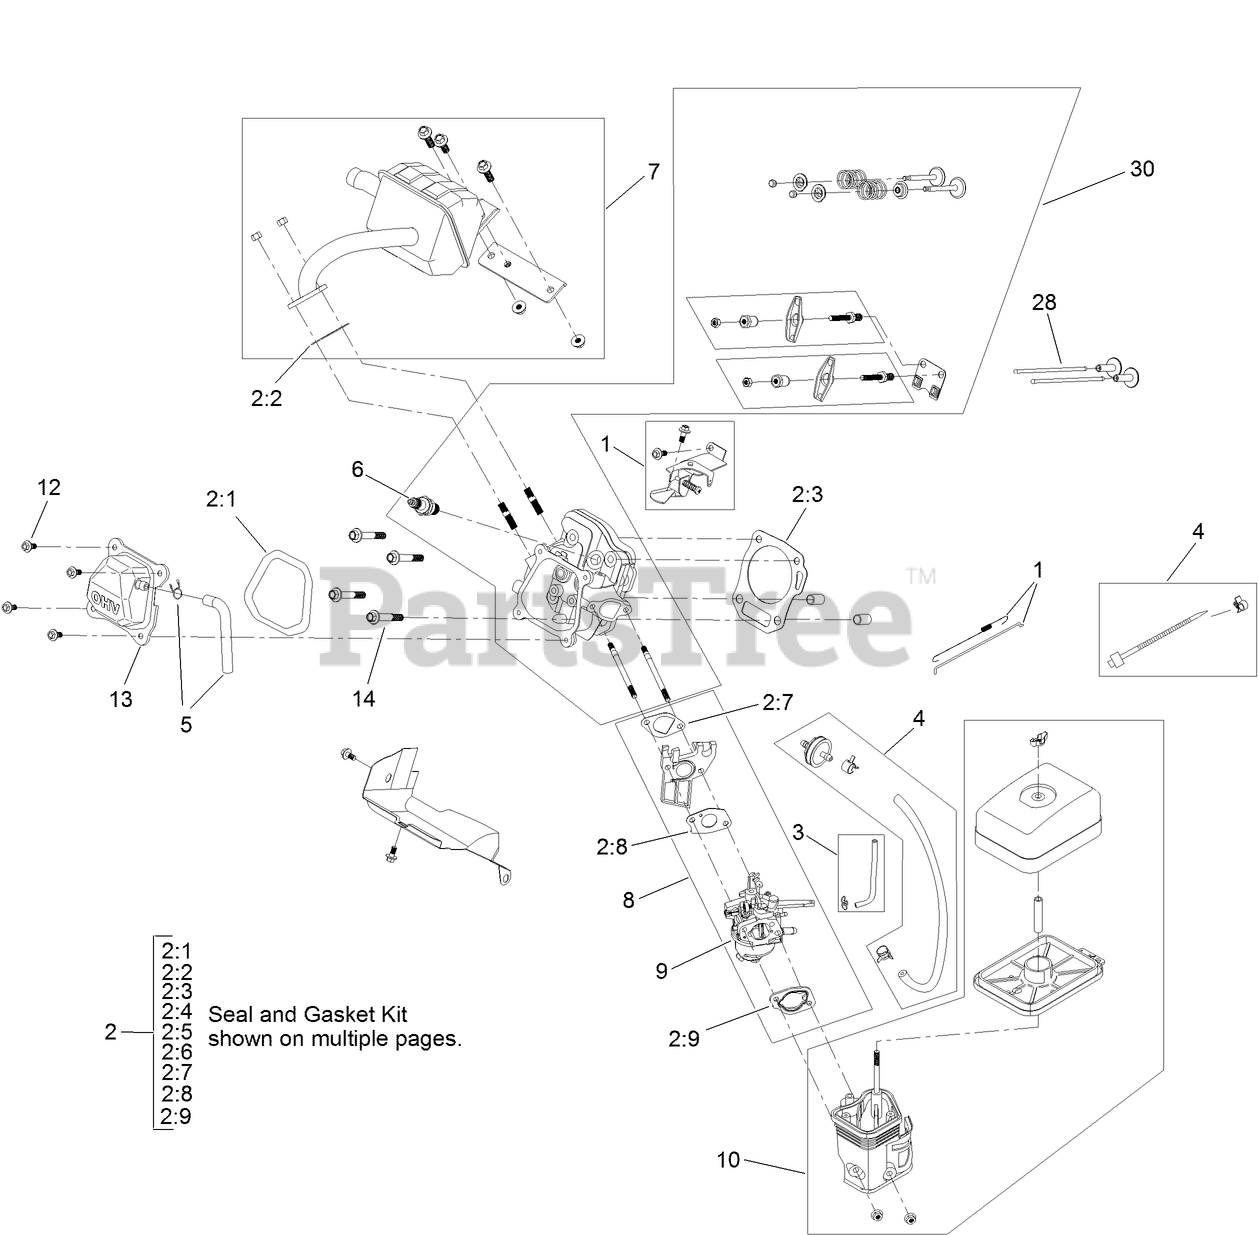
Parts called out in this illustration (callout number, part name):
1	GOVERNOR KIT
2	GASKET AND SEAL KIT
2:1	GASKET-COVER, VALVE
2:2	GASKET-EXHAUST
2:3	GASKET-HEAD, CYLINDER
2:5	SEAL-OIL
2:6	GASKET-COVER, CRANKCASE
2:7	GASKET-CARBURETOR
2:8	GASKET-CARBURETOR
2:9	GASKET-CARBURETOR
3	PRIMER LINE KIT
4	FUEL LINE KIT
5	BREATHER TUBE KIT
7	MUFFLER KIT
8	CARBURETOR KIT
9	CARB REPAIR KIT WITH GASKETS
10	HEATER BOX KIT
12	SCREW-HHF
13	VALVE COVER ASM
14	SCREW-HHF
28	ROD-PUSH
30	COMPLETE HEAD ASM
